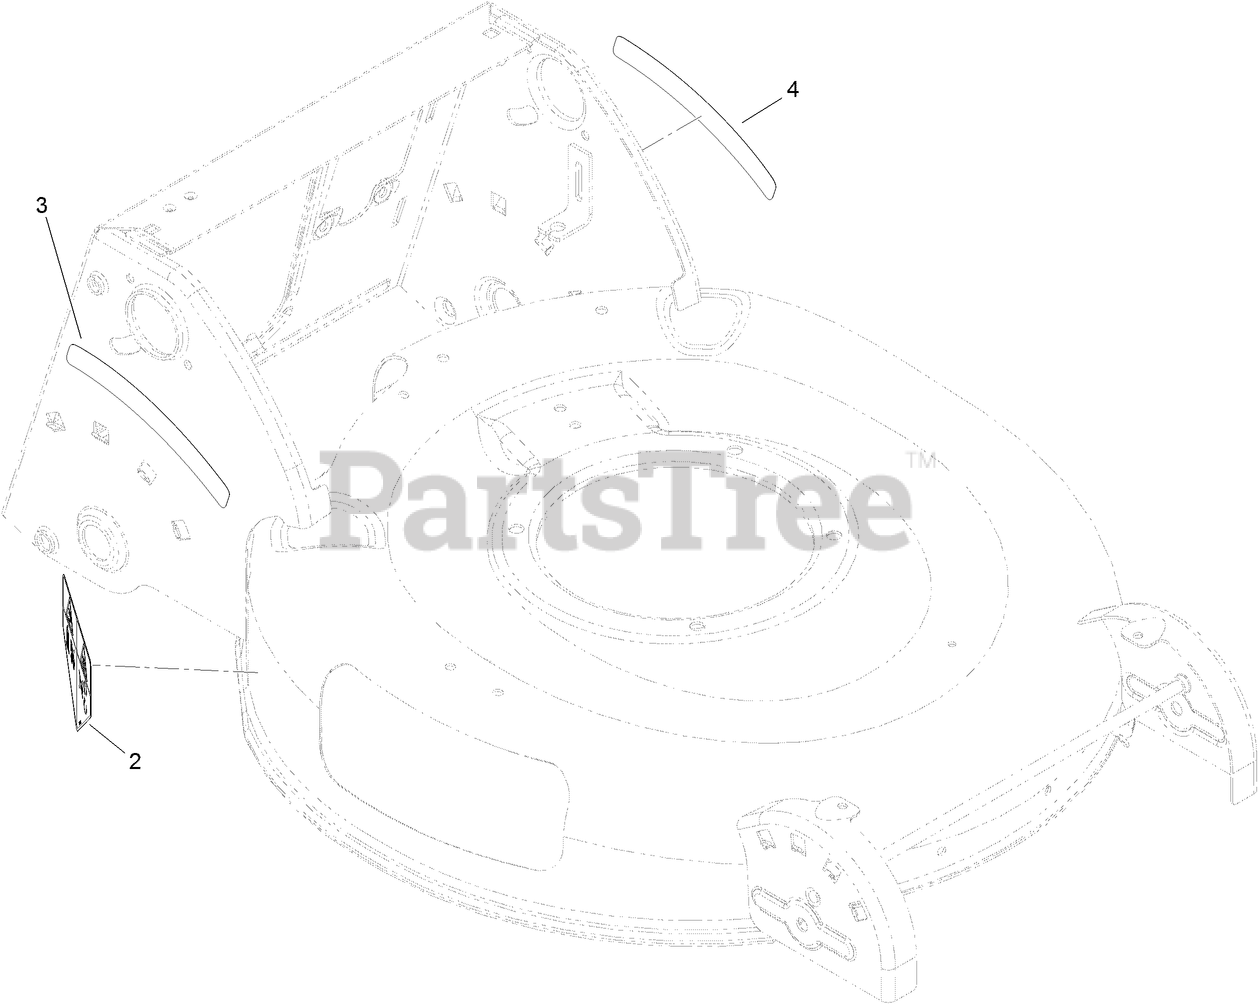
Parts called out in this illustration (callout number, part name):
2	DECAL-DANGER
3	DECAL-HOC, RH
4	DECAL-HOC, LH
